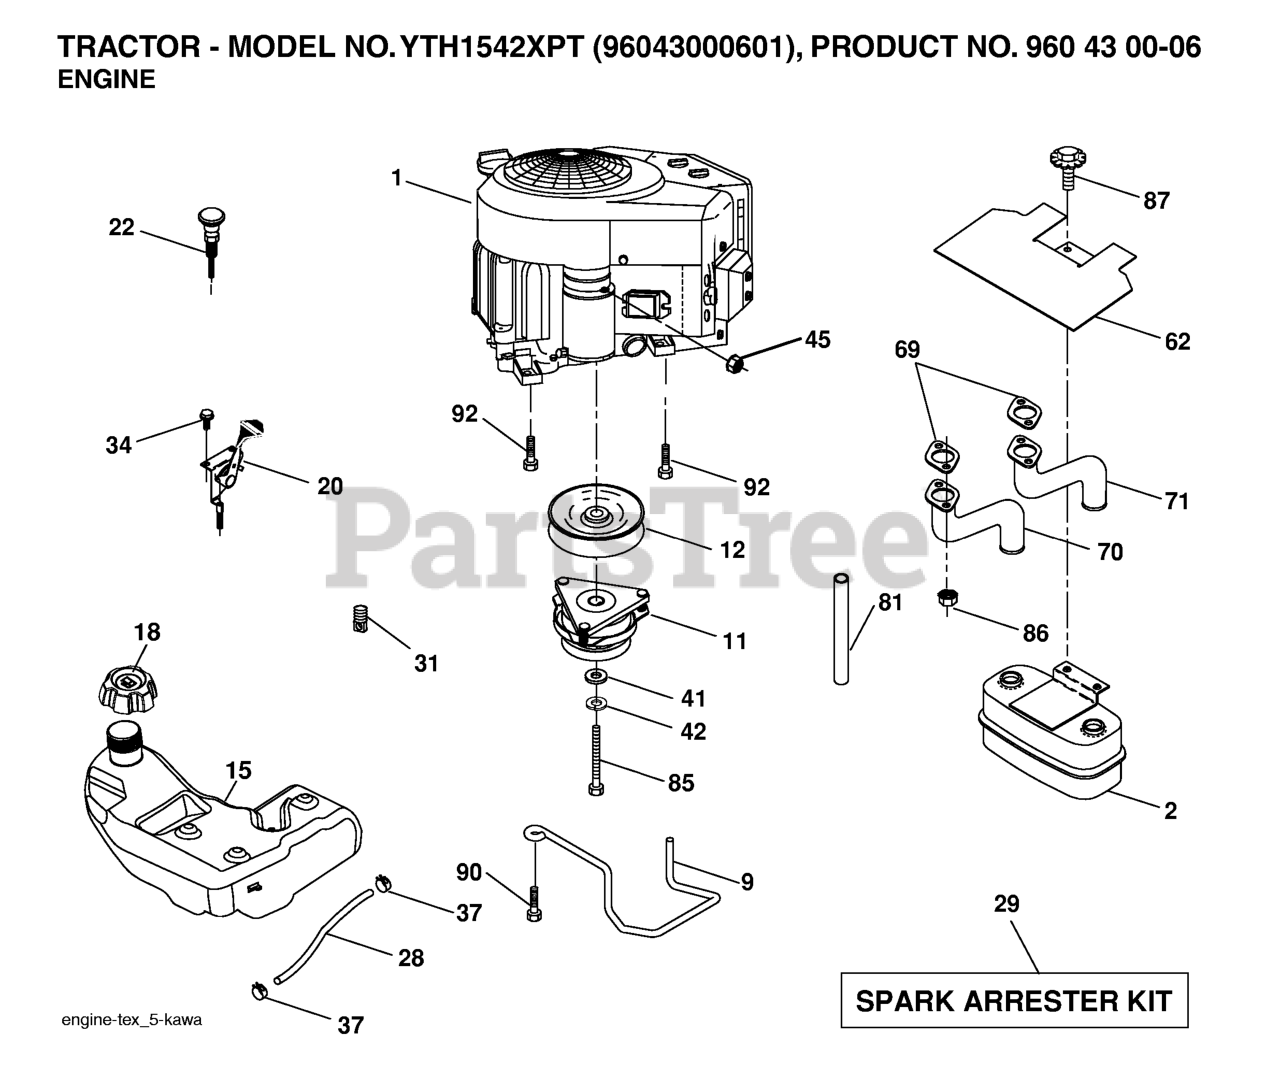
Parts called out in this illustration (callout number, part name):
2	MUFFLER.TWIN.CYL.LOW.TONE
9	KEEPER.BELT.ENGINE.4.2
11	RB.CLUTCH.OGURA.4.4.PD
12	PULLEY.ENGINE.TUFFTORQ
15	TANK.FUEL.4GAL
18	CAP.FUEL.TANK.3"GREY
20	THROTTLE CONTROL
21	SCREW
22	CONTROL, CHOKE
28	LINE.FUEL.64"REAR.EMIS
29	KIT.SPARK ARRESTOR 794945 B&S
37	HOSE CLAMP
42	LOCKWASHER
45	NUT
62	RP SHIELD HEAT MUFFLER
69	GASKET.MUFFLER
70	EXHAUST TUBE LH KAWI
71	EXHAUST TUBE RH KAWI
81	TUBE, DRAIN OIL ASM.
85	BOLT HEX 7/16-20X4-1/4"
86	NUT.HEX.FLANGE.TOPLOCK
87	BOLT.5/16-18UNCX1.W/SEMS.BLK
90	SCREW 3/8-16X1
92	SCREW 3/8-16X1
